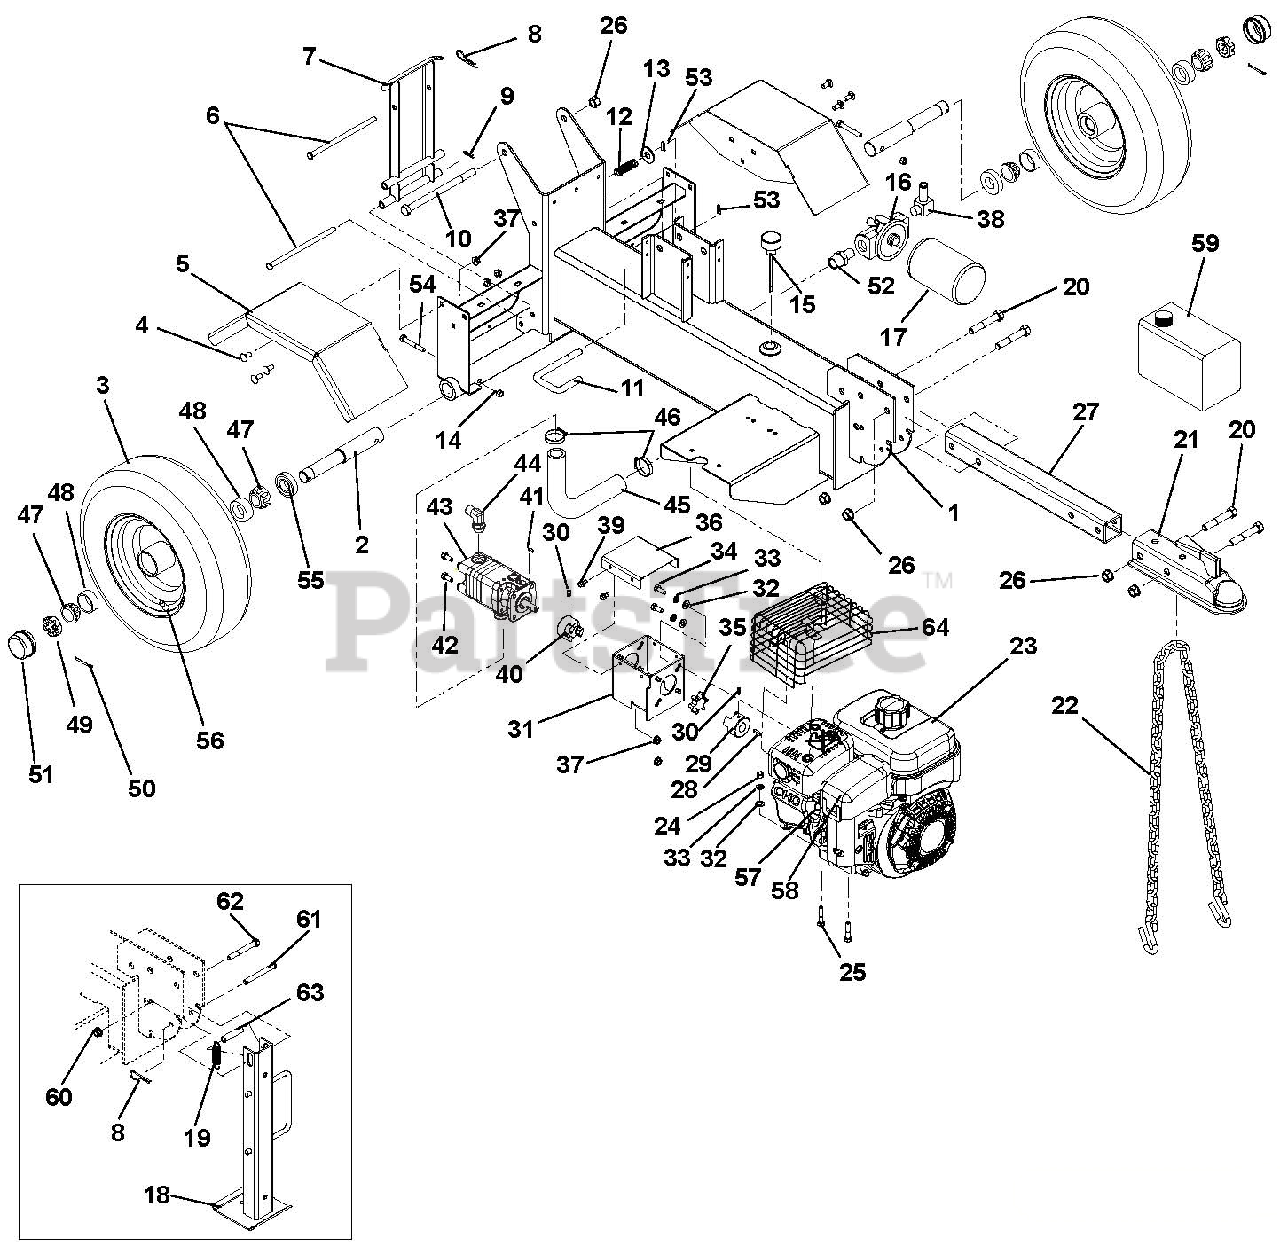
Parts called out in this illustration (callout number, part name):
1	Chassis, Splitter With Safety Decal
2	Axle, Splitter
3	Wheel, Splitter
4	Bolt, Round Head Square Neck .31-18 x .75
6	Pin, Lock
7	Stand, Rear With Decals
8	Hairpin, #7 Clip .094 x .31
9	Pin, Hair #25
10	Bolt, Hex .50-13 x 7.50
11	Lock, Beam
12	Spring, Compression .058 x .65 x 2.13
13	Washer, Flat Steel .563 x 1.38 x .109
14	Nut, Locking Center .31-18
15	Breather, Dipstick
16	Head, Filter 3/4 NPT Bypass
17	Element, Filter
18	Stand, Jack
19	Spring, Tension .063 x .625 x 2.50
20	Bolt, Hex .50-13 x 3.00 Grade 5
21	Hitch, Ball 2-Inch
22	Chain, Safety
23	Engine, Subaru SP170, CARB
24	Nut, Hex .31-18
25	Bolt, Hex .31-18 x 1.50
26	Nut, Locking Center .50-13
27	Bar, Hitch With Decals
28	Key, Square .188 x .75 x .188
29	Hub, Drive Coupling 3/4 Inch
30	Screw, Set .25-20 x .75 Socket Head Cup Point Nyloc
31	Bracket, Pump Mount
32	Washer, Flat Steel .344 x .688 x .065
33	Washer, Locking .312 x .097 Heavy
34	Bolt, Hex .31-24 x .75
35	Spider, Urethane
36	Cover, With Decals
37	Nut, Locking Top Flange .31-18
38	Fitting, Hydraulic 4501-10-12-FG
39	Screw, Tapping .25-20 x .50 Hex Washer Head Thread Rolling
40	Hub, Drive Coupling 1/2 Inch
41	Key, Woodruff .125 x .50 x .20
42	Bolt, Hex .31-18 x .75
43	Pump, Splitter 11 GPM
44	Fitting, Hydraulic 6801-8-8
45	Hose, Hydraulic Suction 16G4H x 13.5
46	Clamp, Hose 1.50 x .81 x 1.42
47	Bearing, Cone With Grease
48	Bearing, Cup 1.980 x .420
49	Nut, Slotted 1.0-14
50	Pin, Center .15 x 1.50
51	Cap, Dust
52	Fitting, Hydraulic 5404-12-12
53	Clip, Spring
54	Bolt, Hex .31-18 x 2.25
56	Valve Stem Assembly
57	Spark Plug
58	Filter, Air
59	Oil, Hydraulic 2.5 Gallon ISO Grade 32
60	Nut, Locking Top Flange .38-16
61	Pin, Clevis .368/.373 x 3.25
62	Bolt, Hex .38-16 x 3.00
63	Spacer, Wheel
64	Guard, Muffler
